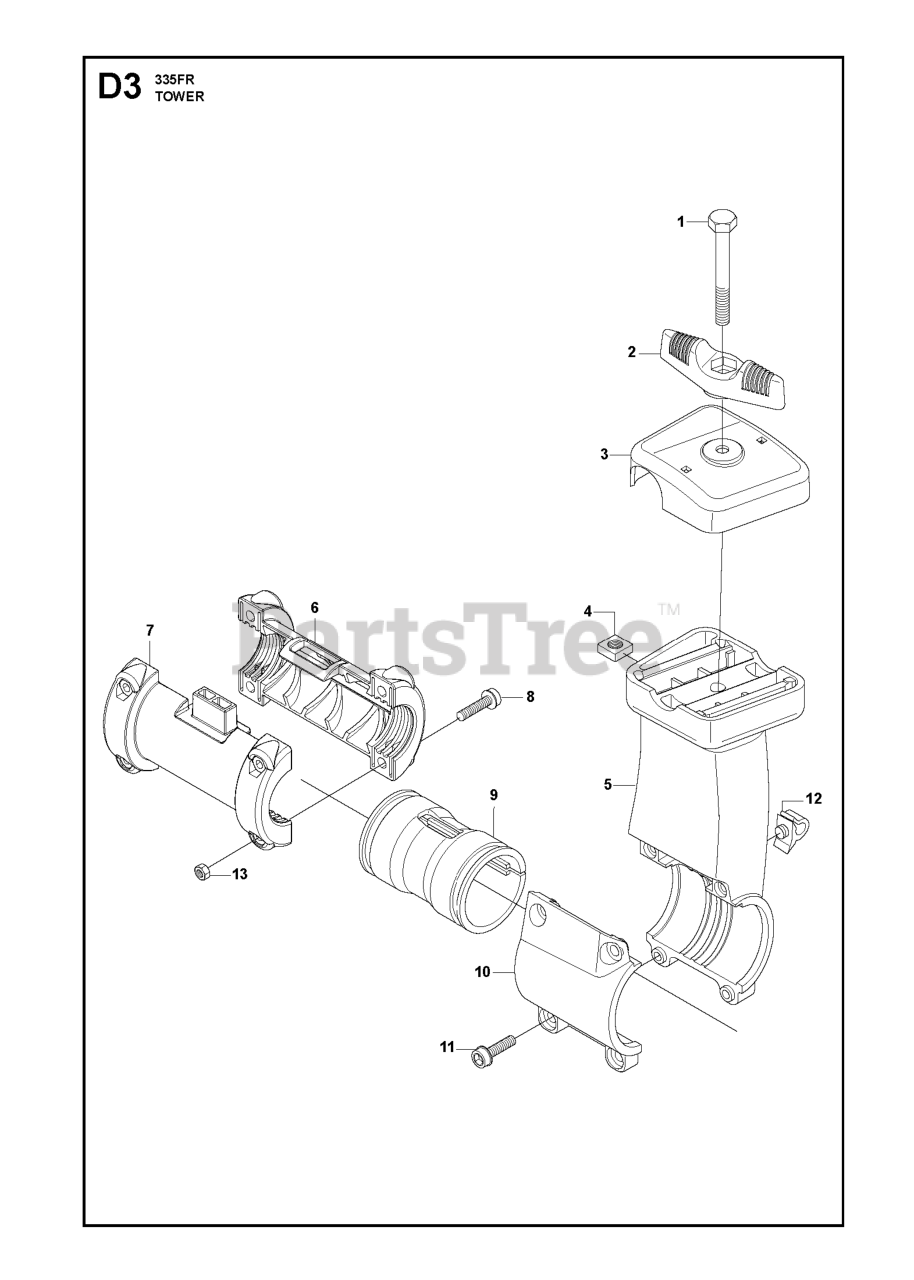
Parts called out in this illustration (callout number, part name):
1	%SCREW
3	PROTECTOR CLAMP
5	BRACKET ASSY
6	CLAMPING SLEEVE
7	CLAMPING SLEEVE ASSY
9	VIBRATIONS ABSORBER
10	COVER, BRACKET
